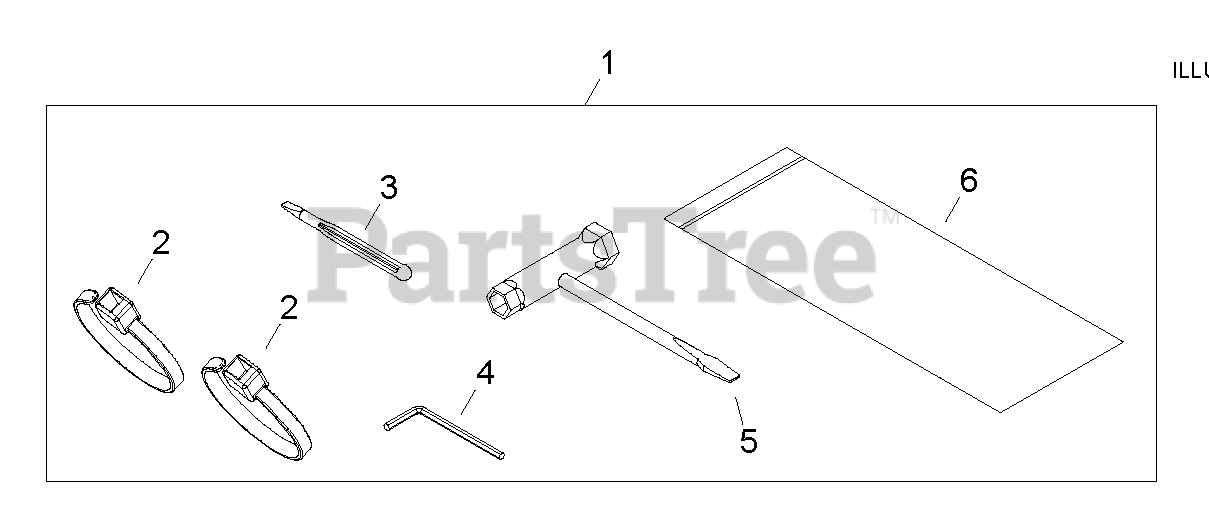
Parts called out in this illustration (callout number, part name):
1	TOOL KIT
2	BAND
3	SCREWDRIVER - PLASTIC
4	HEX KEY - 4mm
5	T-WRENCH - 13X19mm
6	BAG, TOOL
